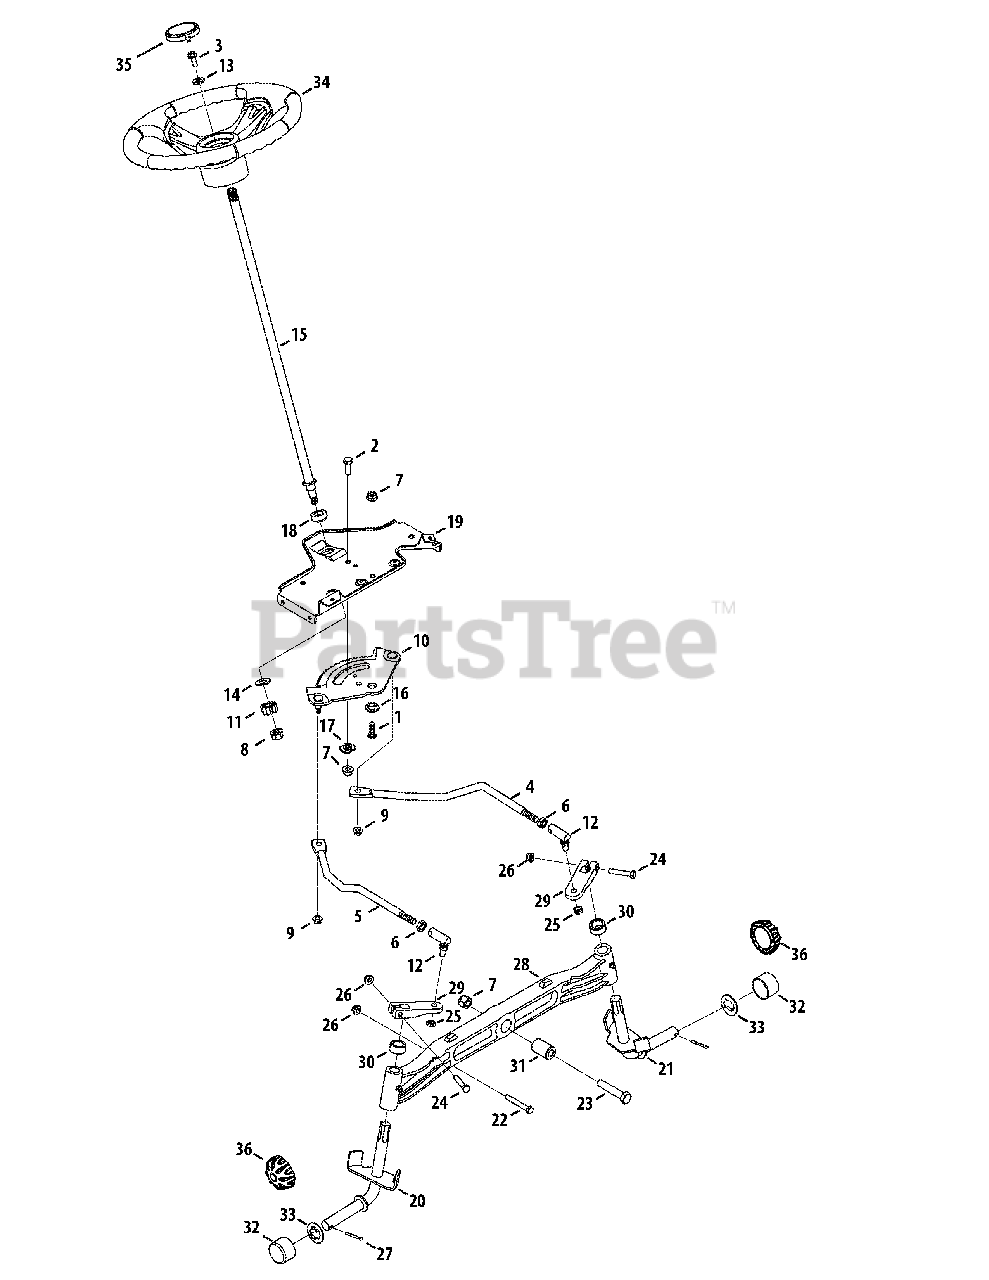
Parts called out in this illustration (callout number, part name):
1	Hex Screw, 3/8-16, 1.00, Gr5, Spec
2	Hex Screw, 3/8-16, 1.00, Gr5, Std
3	Hex Screw, 5/16-18, 1.00, Gr5, Lock
4	Link, Drag LH
5	Link, Drag RH
6	Nut, Jam, 7/16-20, Gr2
7	Nut, Flange Lock, 3/8-16, Grf,
8	Nut, Flange Lock, 7/16-20, Grb, Lock
9	Nut, Flange Lock, 5/16-18, Gr5, Sd Lk
10	Gear, Steering, 11/90 Ratio
11	Gear, Pinion, Steering
12	Ball Joint, 7/16-20, Lock
13	Washer, Flat, .406 x .875 x .105
14	Washer, Flat, .51 x 1.12 x .06
15	Shaft, Steering, .625 OD x 24.25
16	Spacer, Shoulder, .385x 1.25 x .3025
17	Spacer, .38 x 1.375, Special
18	Bearing, Flange, Hex 5/8 Pm
20	Axle Ass’y, RH .750 Dia (46" Deck)
21	Axle Ass’y, LH .750 Dia (46" Deck)
22	Hex Screw, 5/16-18, 2.25, Gr5, Std
23	Hex Screw, 3/8-16, 2.50, Gr5, Std
24	Hex Screw, 5/16-18, 1.75, Gr5, Std
25	Nut, Hex Lock, 3/8-24, Grb
26	Nut, Flange Lock, 5/16-18, Grf
27	Pin, Cotter, 5/32, 1.25
28	Axle, Pivot Bar, Cast
30	Spacer, .71 ID x .125 OD x .56
31	Spacer, .385 x 1.00 x 1.5075
32	Cap, Bumper
33	Washer, Flat, .350 x 1.559 x .062
34	Wheel, Steering, 3 Spoke, Softgrip
35	Cap, Sprig, Small
36	Cap, Hub
